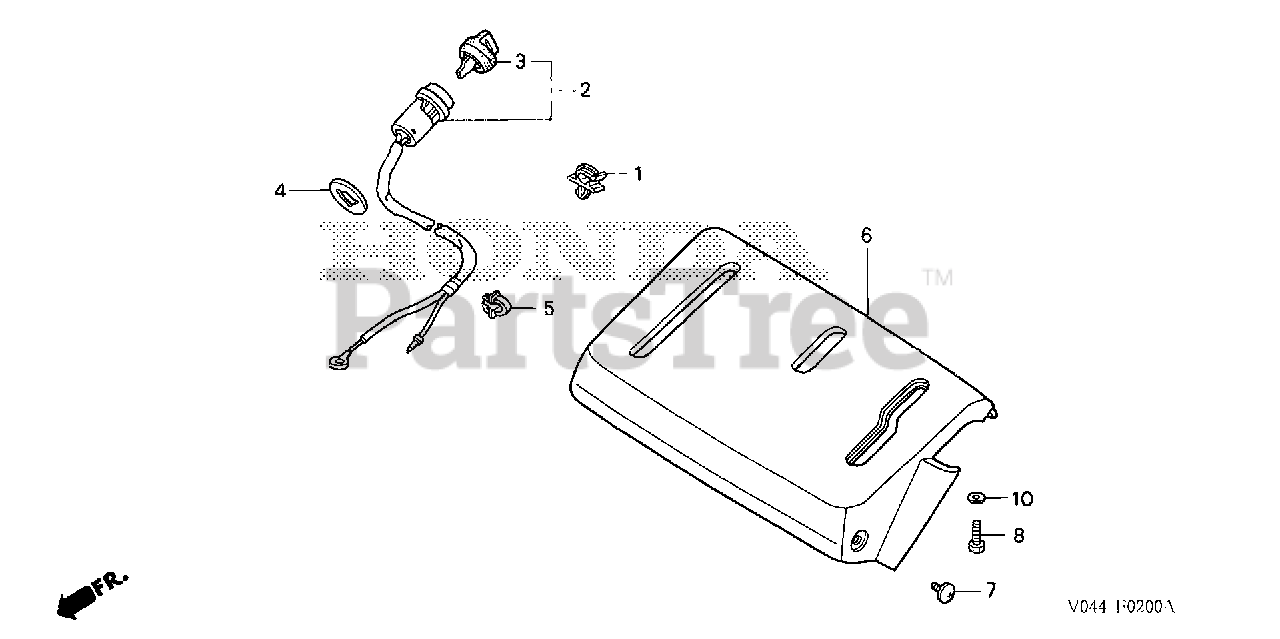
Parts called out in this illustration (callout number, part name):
1	CLIP, IGNITION WIRE (8MM)
2	SWITCH ASSY., COMBINATION
3	KEY ASSY., COMBINATION SWITCH (RED)
4	SPACER, ENGINE STOP SWITCH
5	HOLDER, STOP SWITCH WIRE
6	PANEL, CONTROL *NH296* (ALPS GRAY)
7	BOLT, CONTROL PANEL
7	SCREW, METER VISOR SETTING
8	BOLT, FLANGE (5X12)
8	BOLT, HEX. (5X12)
10	WASHER, PLAIN (5MM)
